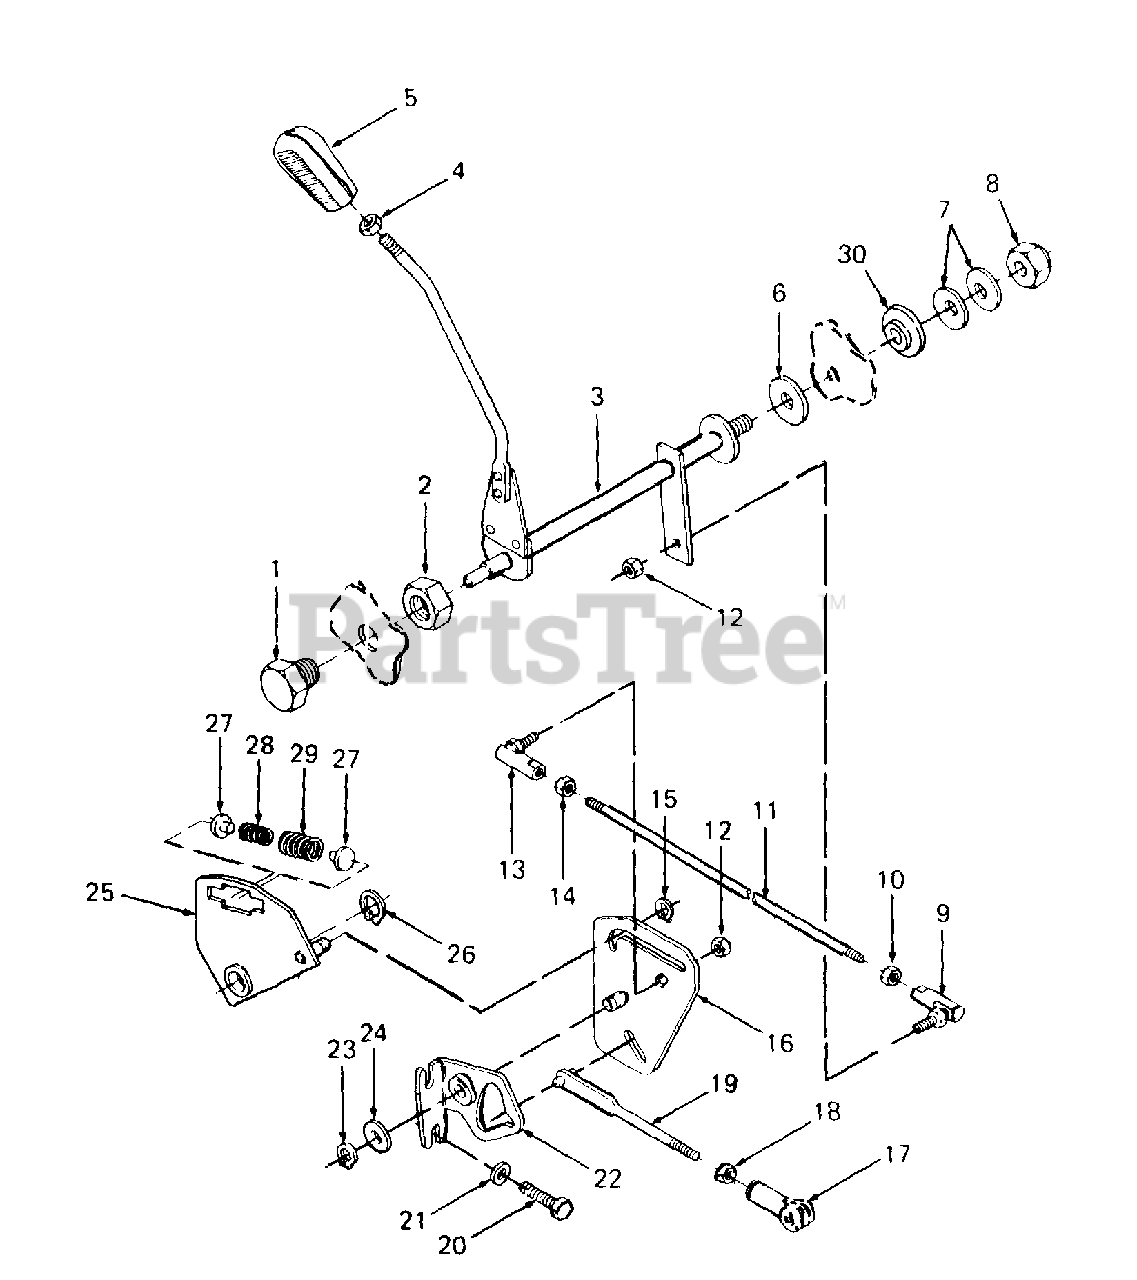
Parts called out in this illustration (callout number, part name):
1	Screw, Rockshaft Bearing, 314-16 x .75 Lg
2	Nut, hex Jam, 3/4-16 GR5
3	Shaft Assy, Cross
4	Nut, Hex Jam, 3/8-16 GR5
5	Knob, Speed Control
6	Disc, Friction
7	Washer, Bell
8	Nut, Hex Top Lock, 1/2-20
9	Ball Joint, 5/16-24
10	Nut, Hex Jam, 5/16-24
11	Rod, Connecting
12	Nut, Hex Patch Lock, 5/16-24
13	Sall Joint, 5/16-24 LH Trd
14	Nut, Hex Jam, 5/16-24 LH Trd
15	Ring, Retaining, .375
16	Cam, Control
17	Clevis Adjustment
18	Nut, Hex Jam, 3/8-24 GR5
19	Rod, Control
20	Screw, Hex Cap, 3/8-16 x 1.5 Lg GR5
21	Washer, Flat, .385 x .87 & .06 Thk HDN
22	Bracket, Cam Pivot
23	Ring, Snap, .500
24	Washer, Flat, .510 x 1.0 x .060 Thk
25	Plate Assy, Damper Spring
26	Ring, Snap, .625
27	Pin, Spring Guide
28	Spring, Compression
29	Spring, Compression
30	Spacer, Shouldered
